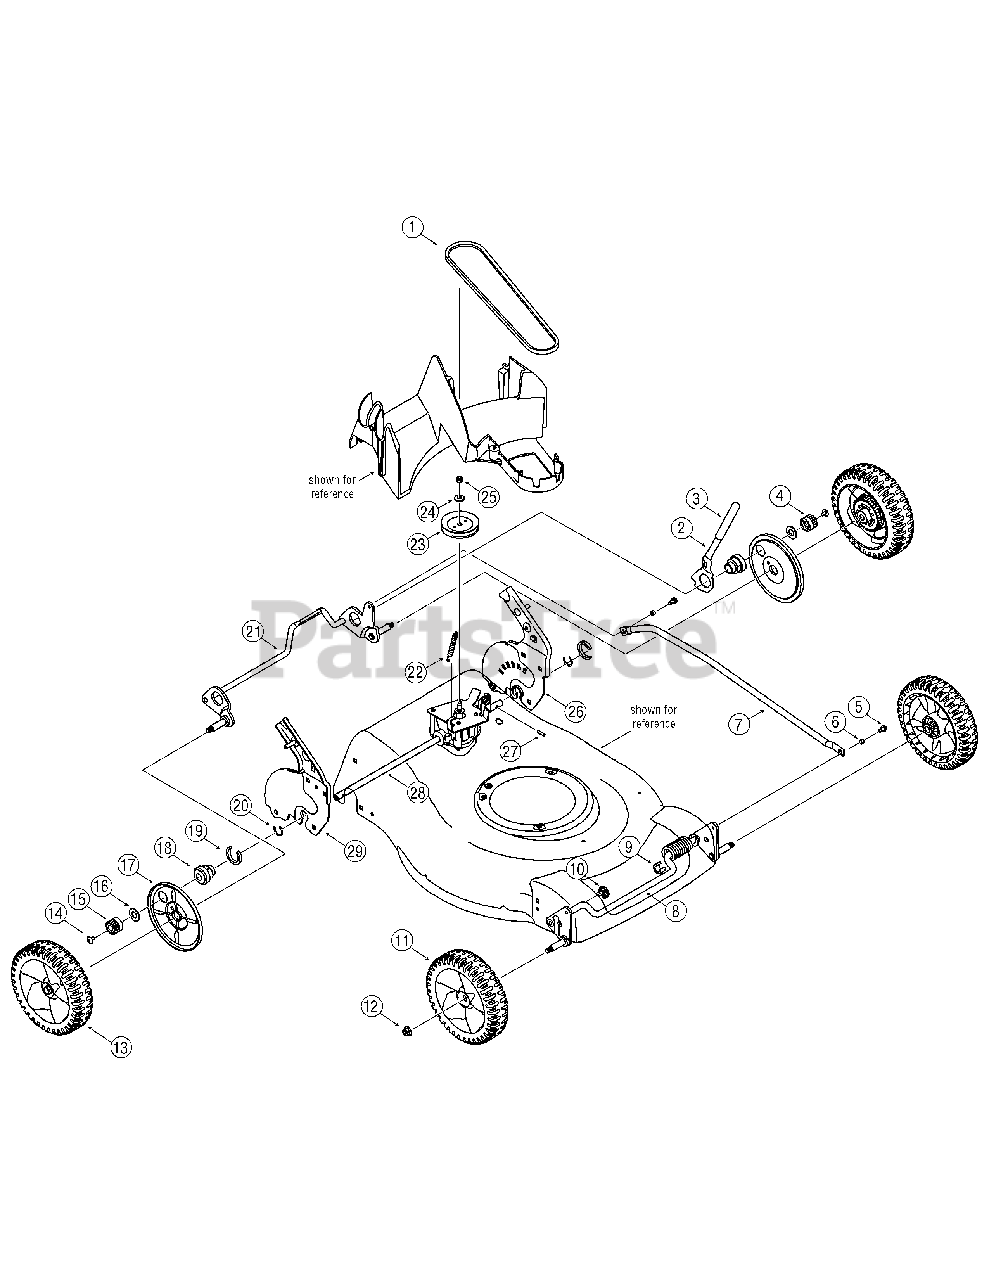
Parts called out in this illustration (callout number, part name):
1	V-Belt
2	Spring Lever
3	Foam Grip
4	Spur Gear, 14T - LH
5	TT Screw, 1/4-20 x 0.50
6	Spacer
9	Clip Spacer
10	Split Hex Flange Bearing
11	Front Wheel
12	Flange Lock Nut, 3/8-16
13	Rear Wheel
14	Screw, 1/4-20 x .39
15	Spur Gear, 14T - RH
16	Flat Washer
17	Wheel Dust Cover
18	Transmission Bearing Support
19	Clip Spacer
20	Retaining Ring .875
22	Extension Spring
23	Pulley, 3.36 OD
24	Bell Washer, .375 x .870 x .063
24	Spacer, .375 ID x .255 Lg.
25	Hex Lock Nut, 5/16-24
25	Hex Lock Nut, 5/16-16
27	Dowel Pin
28	Transmission Assembly
